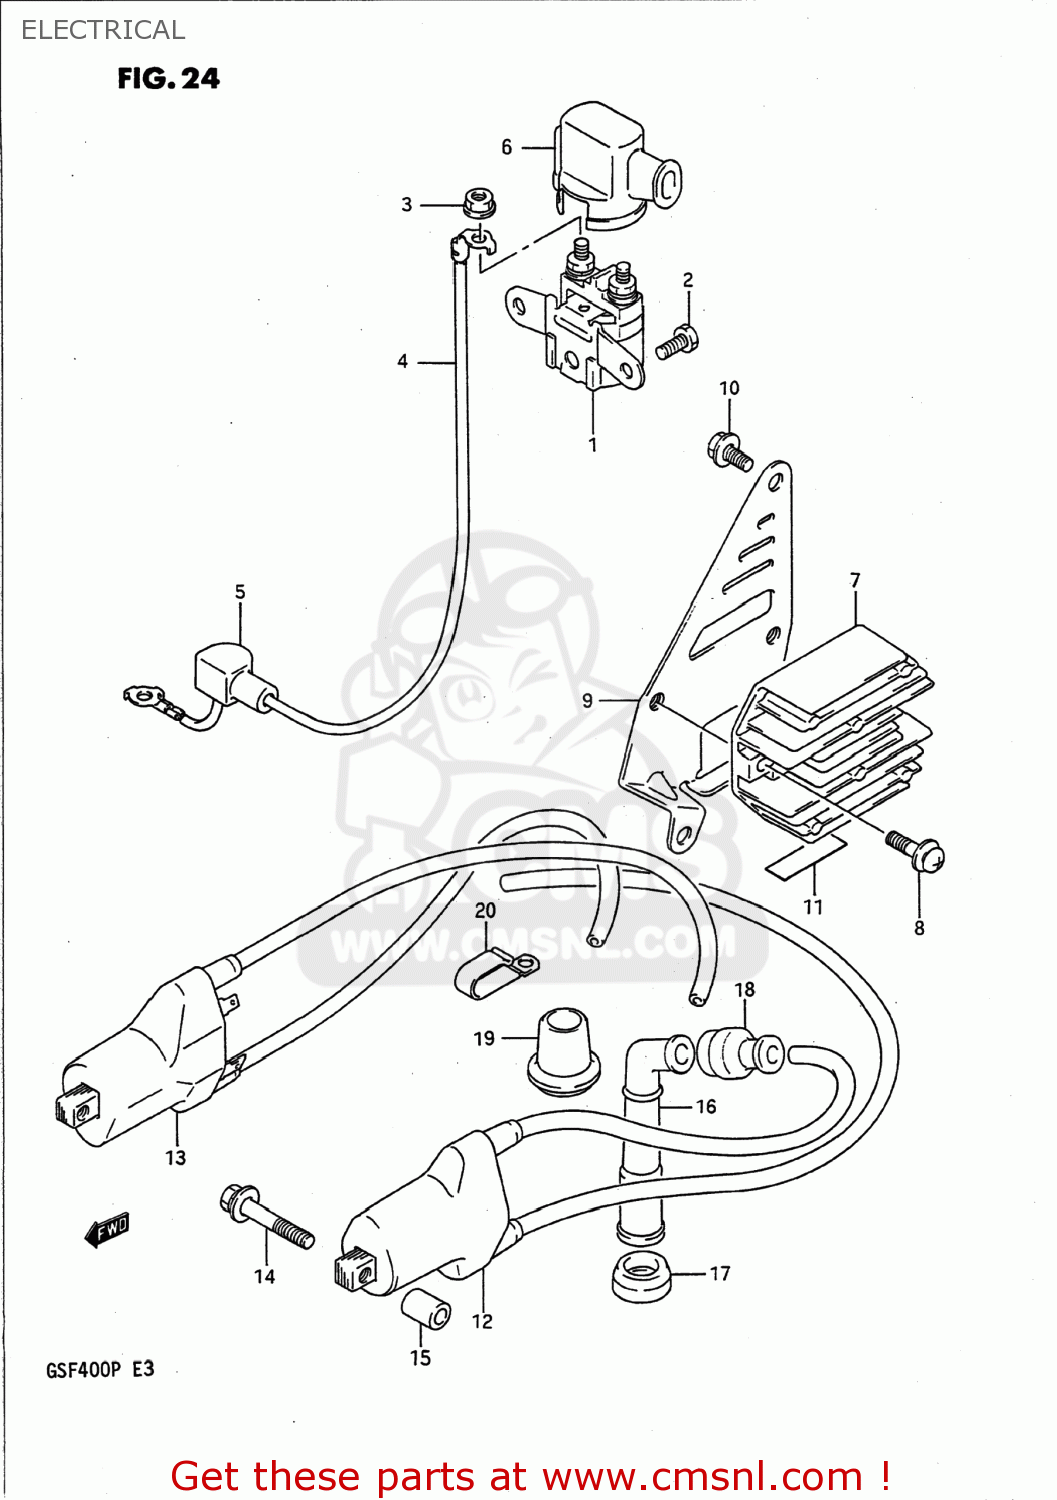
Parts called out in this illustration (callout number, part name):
1	RELAY ASSY,STARTING MOTOR
2	SCREW(6X10)
3	NUT
4	WIRE,STARTER MOTOR LEAD
5	CAP,STARTER MOTOR TERMINAL
6	CAP,STARTER RELAY
7	RECTIFIER ASSY
8	SCREW
9	BRACKET,RECTIFIER
10	BOLT
11	PROTECTOR(12X40)
12	COIL ASSEMBLY,IGNITION
13	COIL ASSY,IGNITION 2-3
14	BOLT
15	SPACER(6.2X12X16)
16	CAP,SPARK PLUG
17	SEAL,SPARK PLUG
18	SEAL,HIGH TENSION CORD
19	COVER,SPARK PLUG CAP
20	CLAMP
